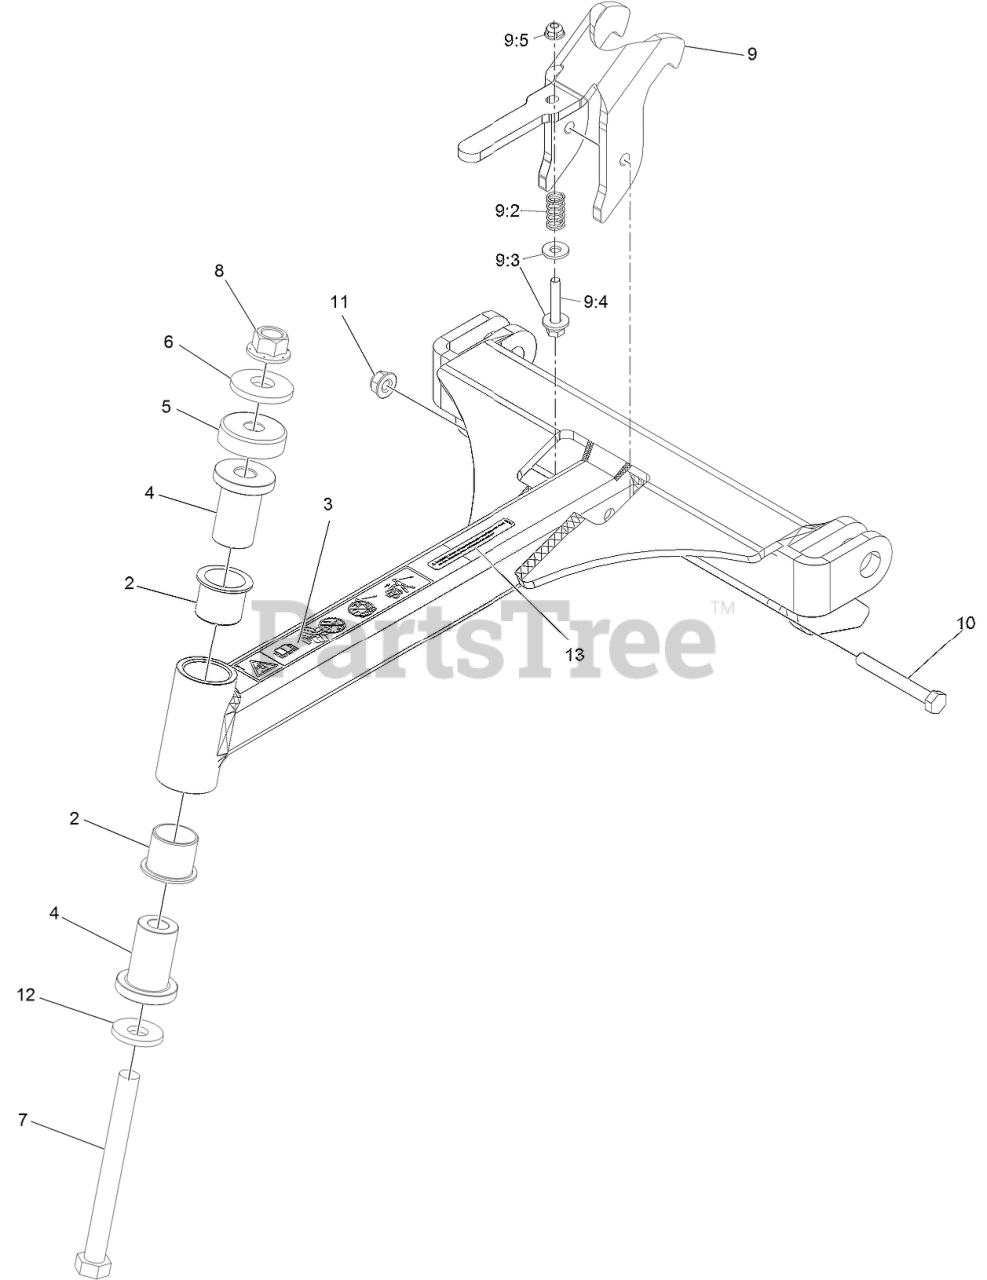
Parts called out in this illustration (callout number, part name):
2	BUSHING-PIVOT
3	DECAL-SULKY HAZARD
4	SPACER, PIVOT
5	COVER, DUST
6	WASHER-BELLEVILLE
7	SCREW-HH
8	Nut-Lock 1/2-13
9	TRANSPORT LATCH ASM
9:2	SPRING, COMPRESSION
9:3	WASHER-FLAT
9:4	SCREW-HH
10	SCREW-HH
11	NUT-HF, NI
12	WASHER-SPRING
13	DECAL-WARNING
